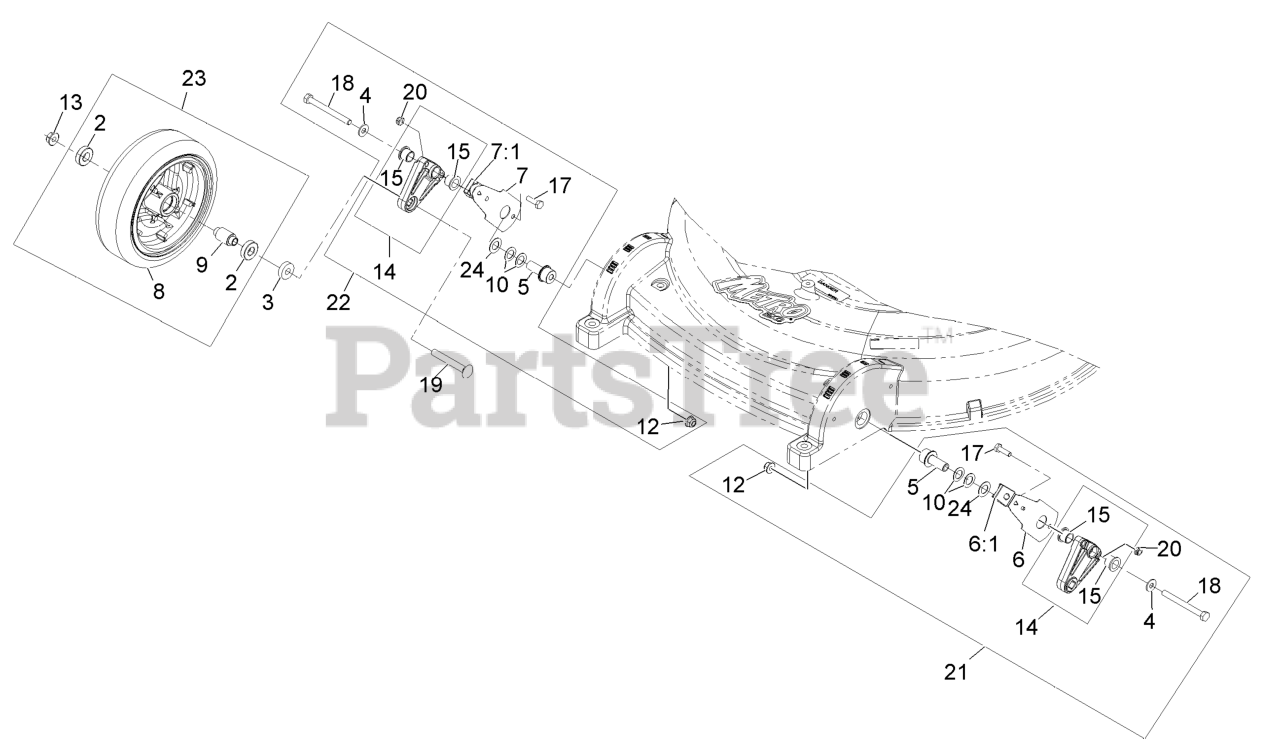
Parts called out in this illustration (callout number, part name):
2	BEARING-WHEEL
4	WASHER-FLAT
5	BUSHING-PIVOT, WHEEL
6	KIT,SPRING ARM FRONT LH
6:1	KNOB-ARM
7	KIT,SPRING ARM FRONT RH
7:1	KNOB-ARM
8	ASM,8" WHEEL AND TIRE
9	SPACER-WHEEL, FRONT
10	WASHER-CONICAL
12	NUT-HF, NI
13	NUT-HF, NI
14	ASM-FRONT WHEEL ARM
15	BEARING-FLANGE
17	SCREW-HH
18	SCREW-HH
19	SCREW-CARR
20	NUT-LOCK, NI
21	ASM-LH PIVOT
22	ASM-RH PIVOT
23	8 INCH WHEEL ASM
24	WASHER-PLAIN
